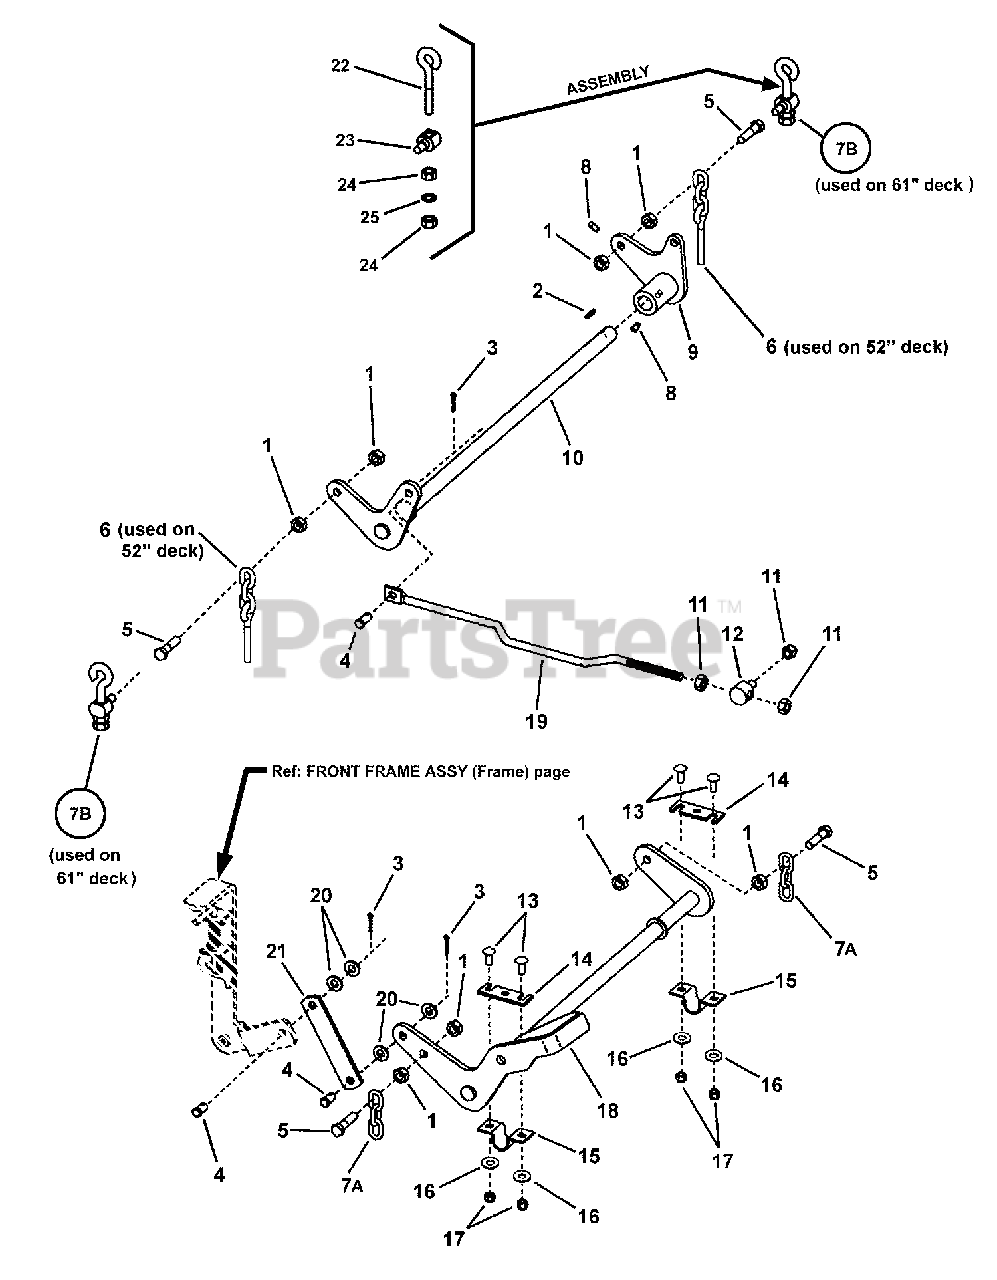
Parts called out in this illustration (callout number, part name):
1	NUT, 1/2-13 Hex Flange GR 5
2	KEY, 3/16" Square x 1-1/2"
3	PIN, 5/32 x 1" Cotter
4	PIN, 1/2 x 1-1/8" Clevis
5	SCREW, 1/2-13 x 2" Hex Head Cap, GR 5
6	ASSEMBLY, Chain & Eyebolt
7A	CHAIN, 3 Links
8	SET SCREW, 5/16-18 Square Head Cup Point
9	WELDMENT, Bellcrank Lift
10	WELDMENT, Rear Lift
11	NUT, 1/2-13 HEX SIDE LOCK
12	SWIVEL, Timing Rod (1/2-13 External Thread)
13	BOLT, 5/16-18 x 1" Short Neck Carriage, GR 5
14	SHIM PLATE
15	BRACKET, Deck Support
16	WASHER, 5/16" Flat
17	NUT, 5/16-18 HEX NYLON LOCK
18	WELDMENT, Front Deck Lift
19	ROD, Timing (1/2-13 Thread)
20	WASHER, .531 I.D. Flat
21	LINK, Front
22	ROD LINK (1/2-13 thread)
23	ROD SWIVEL (1/2-13 thread)
24	NUT, 1/2-13 HEX
25	WASHER, 1/2" Internal Tooth Lock
